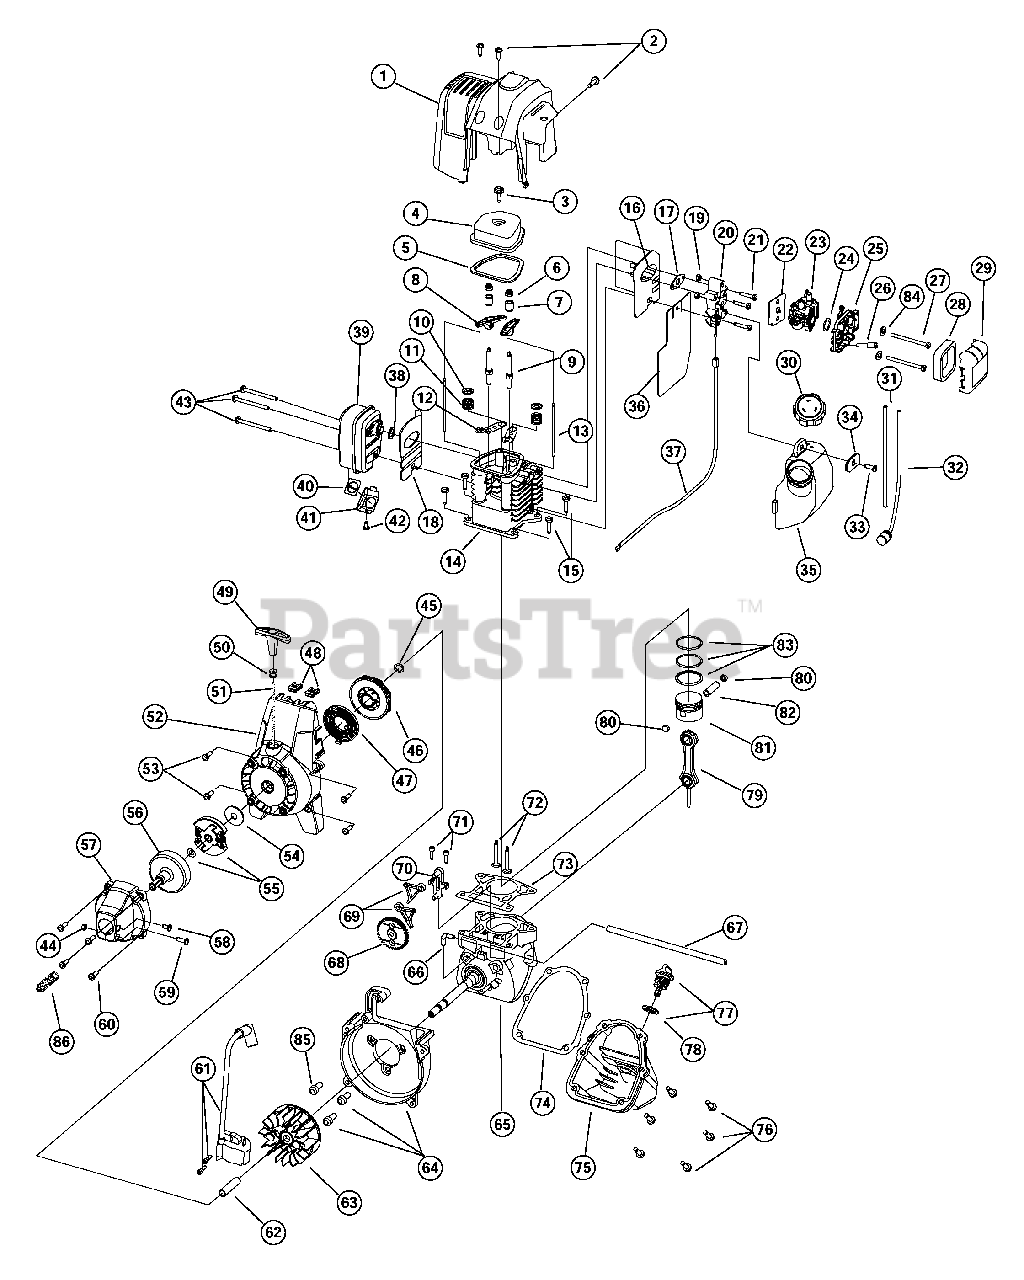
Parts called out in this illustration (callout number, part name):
1	Engine Cover
2	Engine Cover Screws
3	Valve Cover Screw
4	Valve Cover
5	Valve Cover Gasket
6	Rocker Adjustment Nut
7	Rocker Arm Pivot
8	Rocker Arm
9	Rocker Arm Stud
10	Valve Spring Retainer
11	Valve Spring
12	Push Rod Guide
13	Push Rod
14	Cylinder Assembly
15	Cylinder Screw
16	Intake Baffle
17	Carburetor Mount Gasket
18	Muffler Baffle
19	Nut
20	Carburetor Mount
21	Carburetor Mount Screw
22	Carburetor Gasket
23	Carburetor with Primer
24	O-Ring, Carburetor
25	Air Filter/Choke Cover Assembly
26	Breather Tube
27	Air Filter Mounting Screw
28	Air Filter
29	Air Filter Cover
30	Fuel Cap
31	Fuel Return Line
32	Fuel Pick-Up Line with Filter
35	Fuel Tank Assembly
36	Fuel Tank Shield
37	Throttle Cable
38	Muffler Gasket
39	Muffler
40	Spark Arrestor Screen
41	Screen Cover
43	Muffler Mounting Screw
45	Pal Nut Retaining Ring
46	Recoil Pulley
47	Recoil Spring
48	Nut Clip
49	Pull Handle
50	Rope Guide
52	Starter Housing Screw
53	Starter Housing Assembly
54	Clutch Washer
55	Clutch with Spacer
56	Clutch Drum
57	Clutch Cover
58	Anti-Rotation Screw
59	Screw
60	Clutch Cover Screw
61	Ignition Module with Screws
63	Flywheel
64	Shroud Assembly with Screws
65	Crankcase Assembly
66	Oil Seal
67	Bearing
68	Crankshaft Assembly
69	Cam Follower
70	Cam Bracket
71	Cam Bracket Screw
72	Valves, Intake and Exhaust
73	Cylinder Gasket
74	Oil Pan Gasket
75	Oil Pan
76	Oil Pan Screw
77	Dipstick Assembly
79	Connecting Rod
80	Wrist Pin Button
81	Piston
82	Wrist Pin
83	Piston Ring Set
86	Compression Spring
87	Grommet
